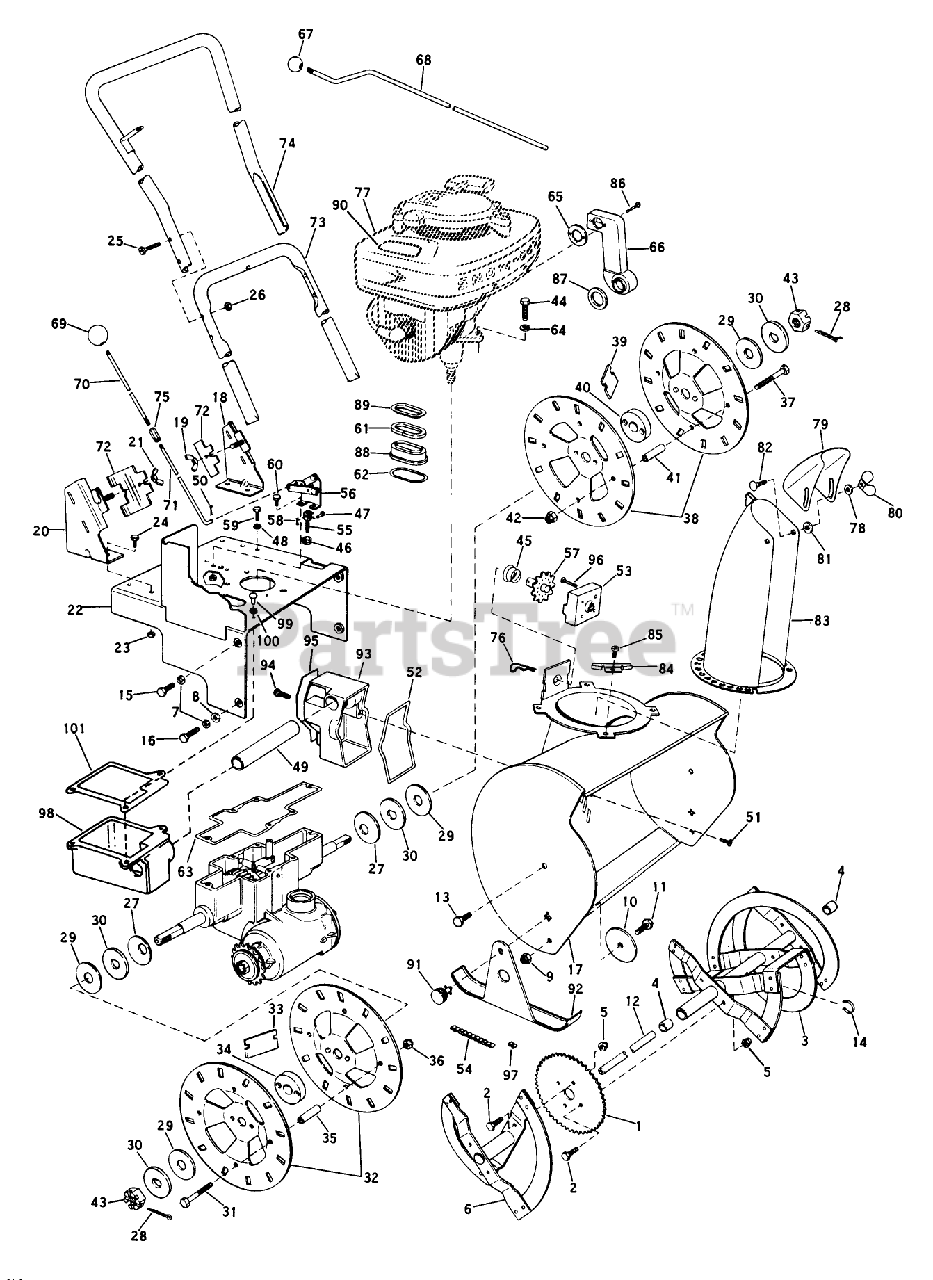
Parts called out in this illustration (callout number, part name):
3	Impeller Assy.
4	Bushing
5	Nut-Huglok
7	Lockwasher-Screw-Hsg. to Base
11	Stud-Front Wheel
13	Screw-Impeller Shaft to Housing
15	Screw-Housing to Base
16	Screw-Housing to Base
24	Screw-Guard to Housing
26	STOP NUT
28	Cotter Pin-Wheel
30	Washer-Steel
43	Nut-Wheel Mtg.
46	Grommet-Base
51	Screw-Muffler to Housing
52	Gasket-Muffler to Housing
54	Drive Chain
62	Gasket-Exhaust
85	Screw-Chute Retainer
96	Drive Screw
